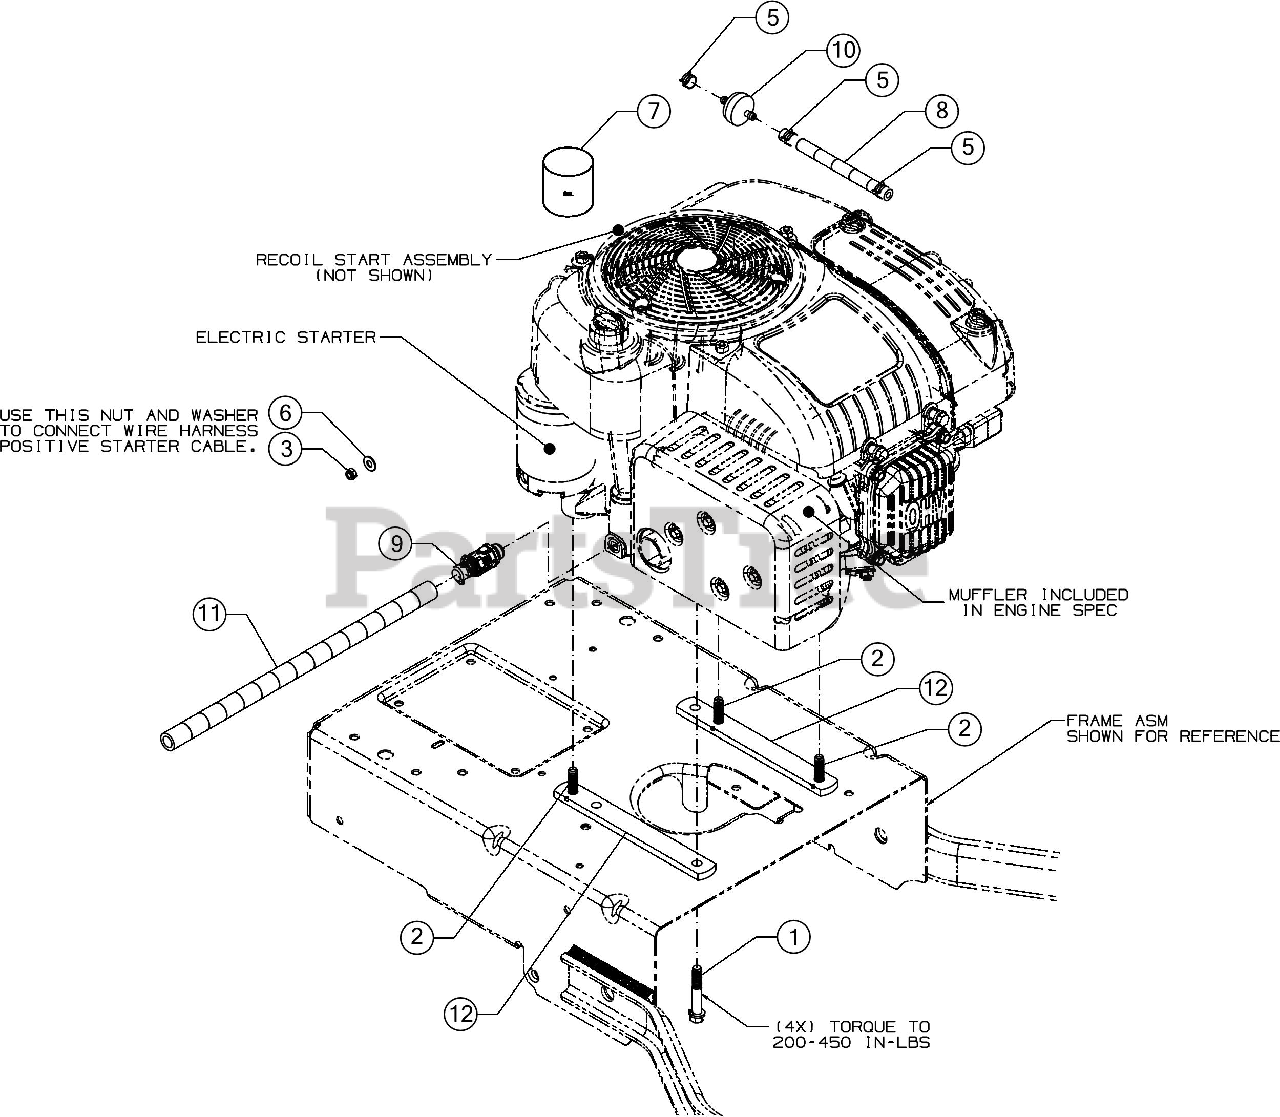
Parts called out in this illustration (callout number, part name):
1	SCREW 3/8-16 X 2.25
2	SCREW 3/8-16 X 1.500
3	HEX NUT
5	HOSE CLAMP 1/20
6	FLAT WASHER
7	OIL 10W30
8	FUEL HOSE LOW PERMEATION
9	OIL DRAIN VALVE
10	FUEL FILTER
11	DRAIN HOSE 14''
12	ENGINE PLATE MTG
